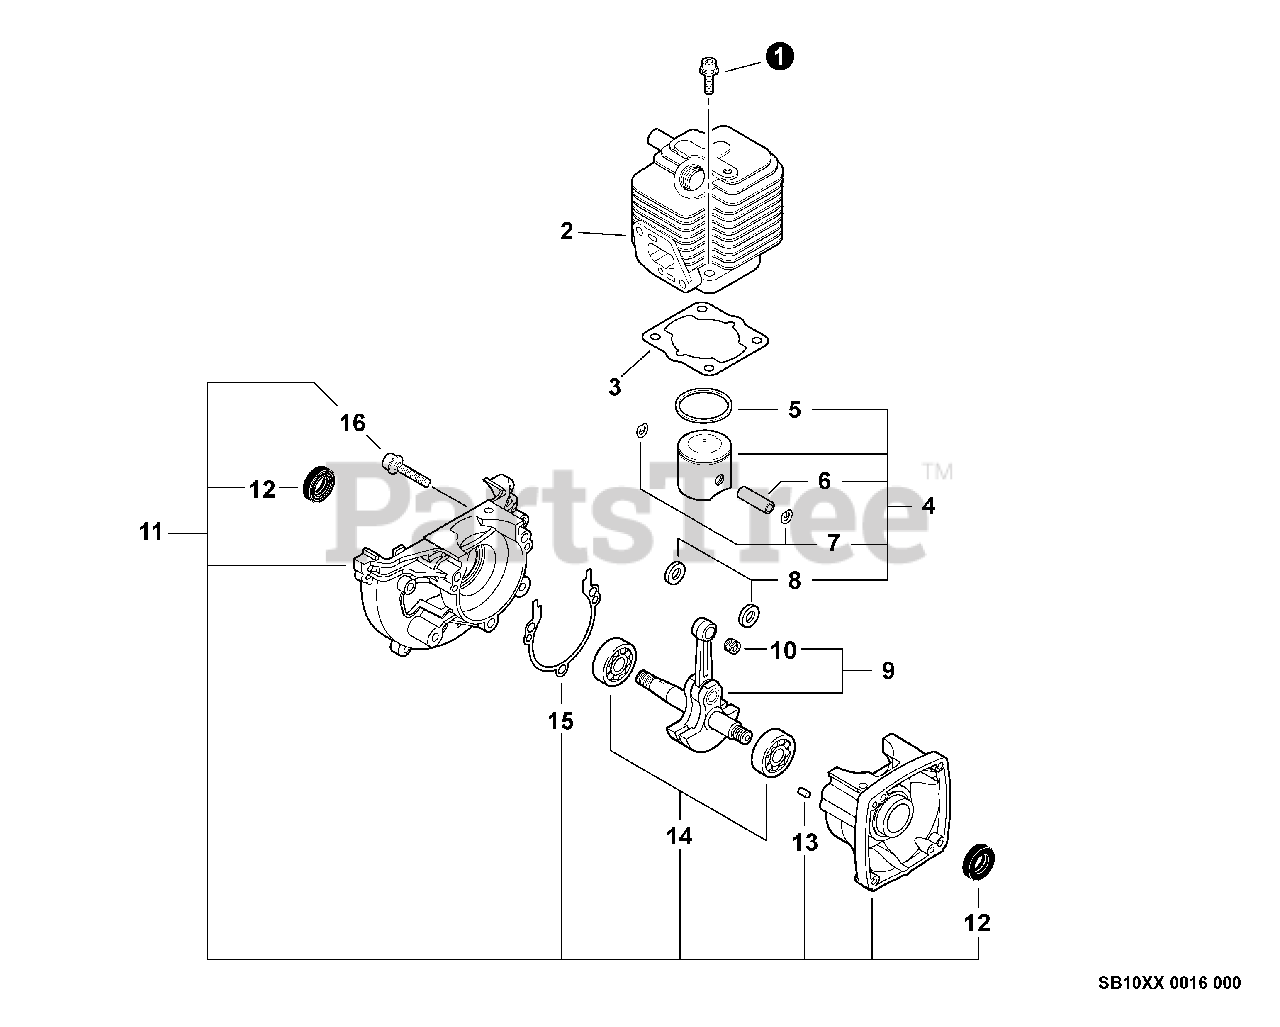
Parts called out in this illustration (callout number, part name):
1	SCREW - 5X22
2	CYLINDER
3	GASKET, CYLINDER
4	PISTON KIT
5	RING, PISTON
6	PIN, PISTON
7	RING, RETAINING
8	SPACER, PISTON
9	CRANKSHAFT ASSY
10	BEARING, NEEDLE - 8
11	CRANKCASE KIT
12	SEAL, OIL
13	PIN - LOCATING
14	BEARING, BALL - 6201
15	GASKET, CRANKCASE
16	SCREW - 5X28
